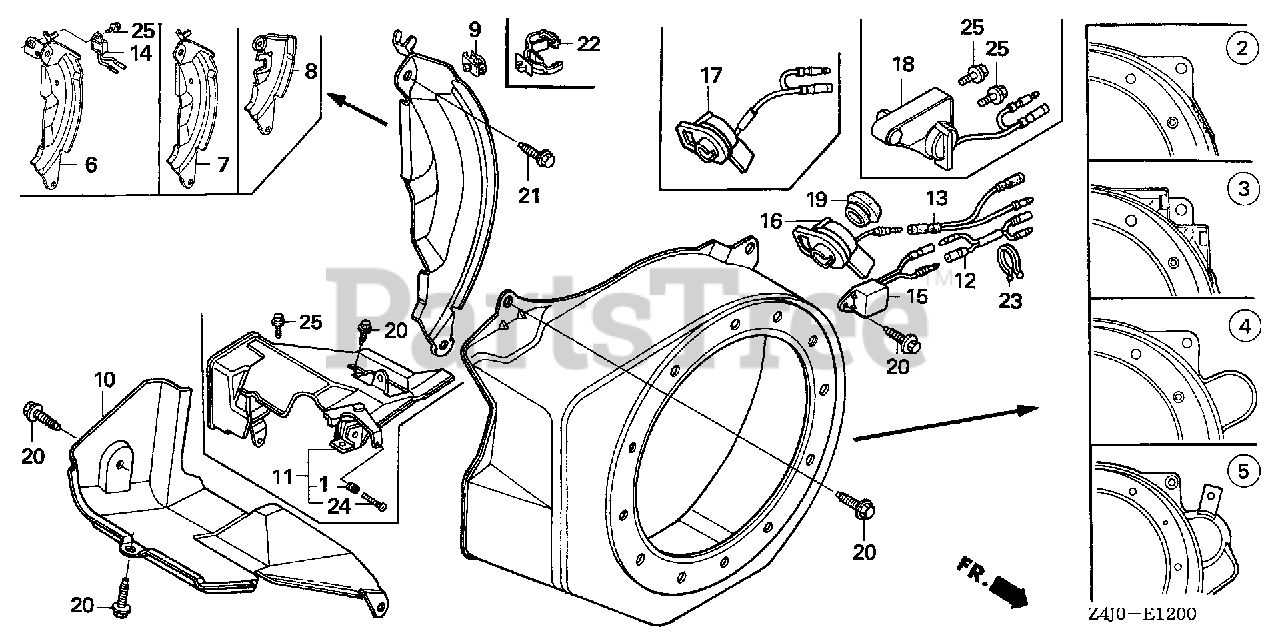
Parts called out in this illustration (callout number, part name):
2	COVER, FAN *NH1* (BLACK)
6	PLATE, SIDE (OIL ALERT)
14	ALERT UNIT, OIL
17	SWITCH ASSY., ENGINE STOP
20	BOLT, FLANGE (6X12) (CT200)
21	BOLT, FLANGE (6X20) (CT200)
22	CLIP, HARNESS
25	BOLT, FLANGE (6X8)
